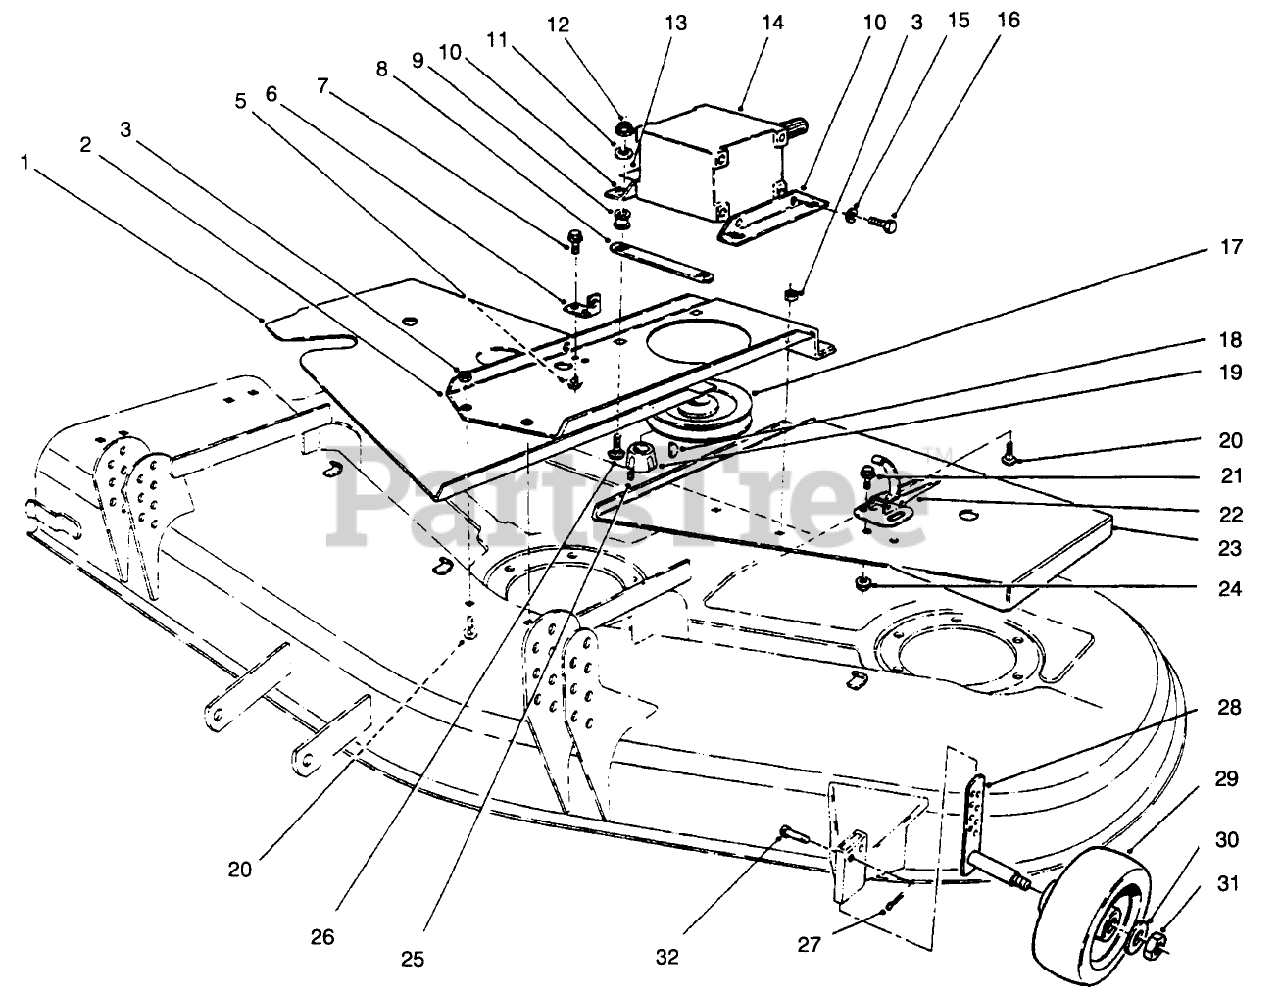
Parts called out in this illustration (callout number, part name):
1	Cover RH
2	Base-Gear Box
3	NUT-HHF, WHIZ
5	NUT-HF
6	Bracket-Extension
7	SCREW-HH
8	Cover-Gear Box
9	MOUNT
10	Bracket-Gearbox
11	WASHER
12	NUT-LOCK, SIDE
13	DECAL-OIL
14	Gearbox
15	WASHER-LOCK
16	SCREW-HH
17	PULLEY
18	KEY-WOODRUFF
19	Bushing-Taper Lock (Incl. Ref. #25)
20	SCREW-CARR
21	SCREW-HWH
22	CLAMP-SLOTTED
23	Cover LH
24	NUT-LOCK, FLANGE
25	SCREW-SET, HSH
26	SCREW-CARR
27	PIN-HAIR
28	GAGE-WHEEL
29	WHEEL-GAGE
30	WASHER-FLAT
31	NUT-LOCK, NI
32	PIN-CLEVIS
